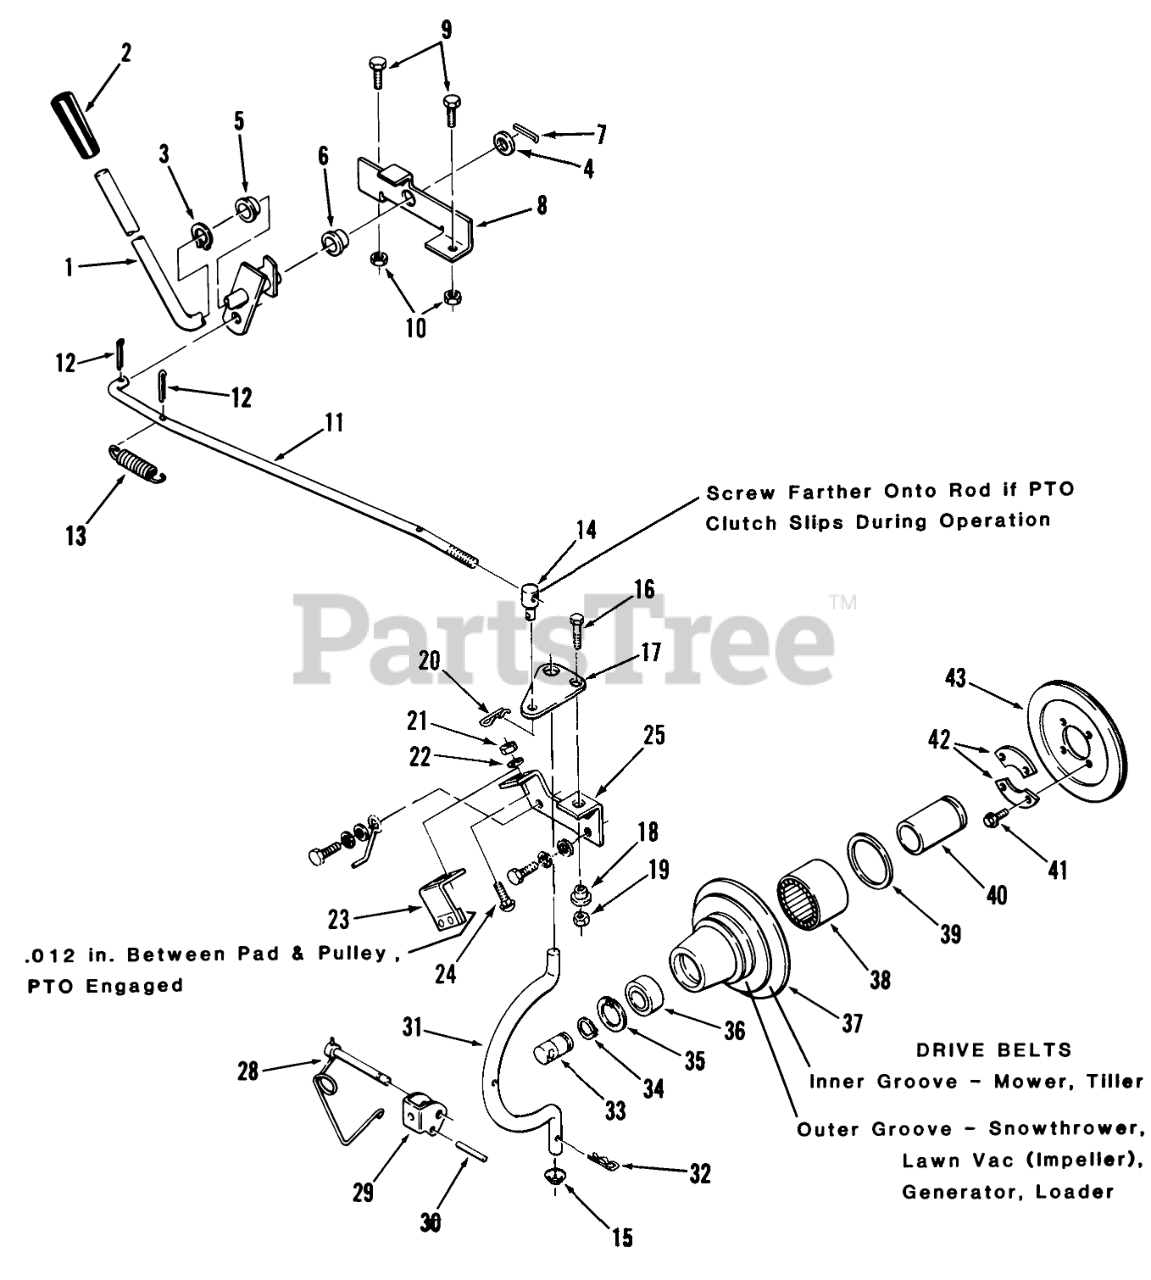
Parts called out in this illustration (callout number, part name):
1	PTO CLUTCH LVR ASM
2	GRIP
3	Grip Ring
4	SHIM-WASHER
5	BUSHING-NYLINER
6	NYLINER BUSHING
7	Pop Rivet
8	SUPPORT-PTO CLUTCH
9	Bolt
10	Nut
11	PT0 Clutch Rod
12	Pop Rivet
13	SPRING
14	TRUNNION
15	RING-REINFORCED CIRC
16	BOLT
17	PLATE R
18	SPACER-LIFT LINK
19	Nut
20	Hairpin Cotter
21	Nut
23	PTO Plate
24	Bolt-Carriage
25	BRACKET
25	BRACKET-ENGINE B
28	Pin
29	Clevis
31	ROD-HOUSING
32	Hairpin
33	SHAFT-PTO
34	RING-SNAP, EXTERNAL
35	Ring-Snap
36	BaIl Bearing
37	Housing-Clutch
38	BRG-NEEDLE OPEN END
39	SEAL-OIL
40	RACE-BEARING
40	BEARING RACE
41	Screw
42	RETAINER
43	Clutch Plate & Facing
